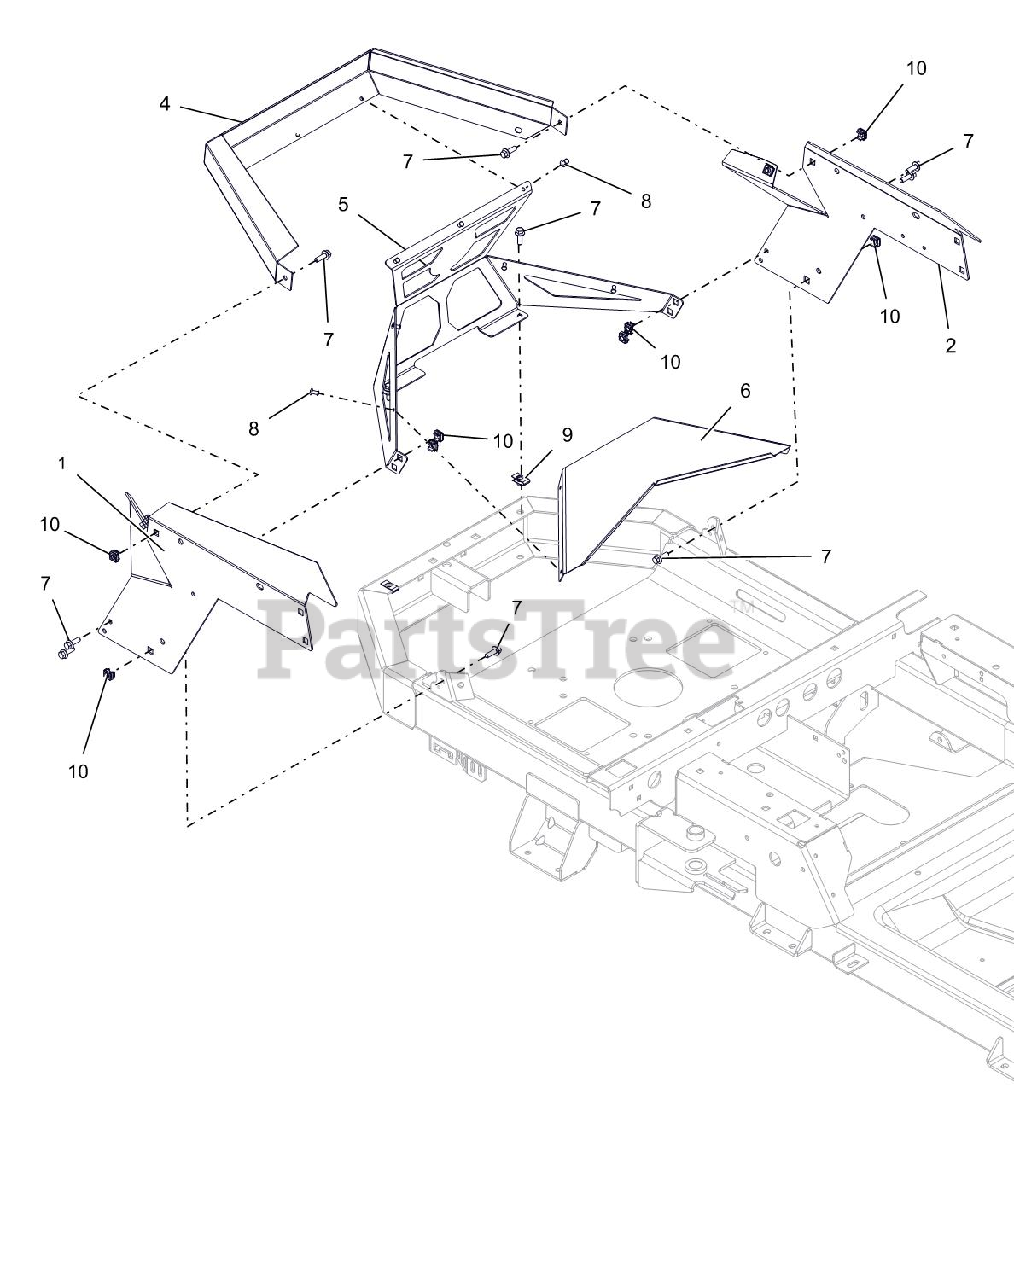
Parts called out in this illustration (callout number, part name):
1	PANEL, RIGHT REAR FENDER MOUNT
2	PANEL, LEFT REAR FENDER MOUNT
4	GUARD, ENGINE WRAP
5	GUARD, ENGINE
6	BAFFLE,ENGINE WRAP
7	BLT,HEX-FLG .25-20X.75 G5 BFP
8	RIVET, #66 STEEL POP PD BLACK
9	NUT-RTNR .25-20X.56
10	NUT RETNR .25-20
